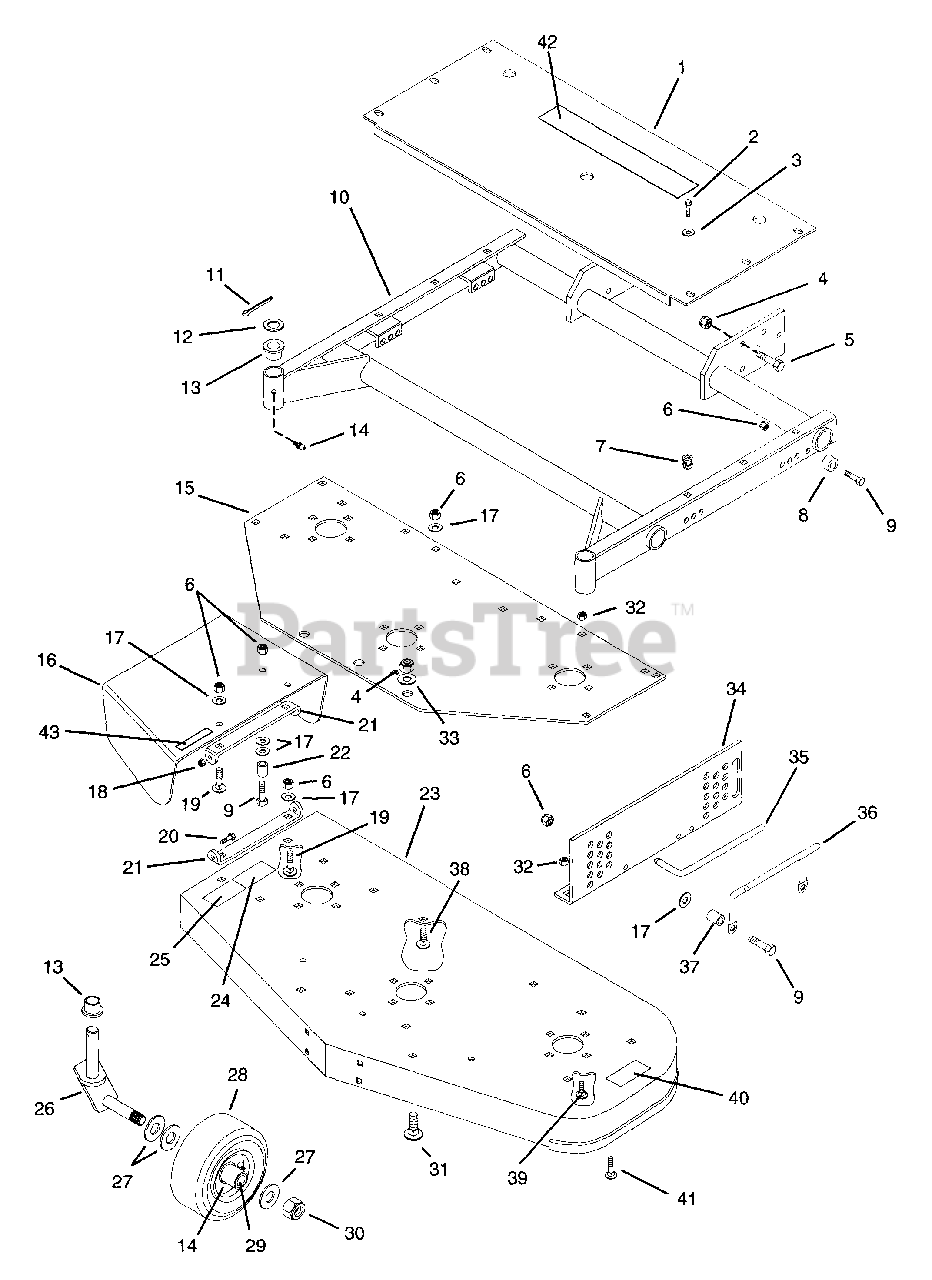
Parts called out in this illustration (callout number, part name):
1	Guard, 50"
2	Screw-Tapping, .25-20 x .50 Hex Slot Head
3	Washer-Flat-Steel .281 x .625 x .065
4	Nut, Locking .50-13
5	Bolt, Hex .50-13 x 1.50
6	Nut-Locking-Nylon .375-16 w/Insr Grade 2
7	Grommet, Plastic
8	Bushing, .391 x .626 x .670
9	Bolt-Hex .38-16 x 1.50 Grade 5
10	Weldment, Mower Frame
11	Pin, Cotter .187 x 1.50
12	Race, Bearing Thrust
13	Bushing-Flange 1.03 x 1.75 x .750 Nylon
14	Fitting, Lube .25-28
15	Plate, Support
16	Shield, Safety Ext. 50" Mower
17	Washer-Flat-Steel .406 x .812 x .065
18	Nut, Locking .25-20
19	Bolt, Round Head Square Neck .375-16 x 1.00
20	Bolt, Hex .25-20 x .875
21	Bracket, Chute
22	Stop, Chute
23	Weldment, 50" Mower Fabricated
24	Decal, Danger Hand
25	Decal, Warning Eye
26	Weldment, Caster Fork
27	Washer-Flat-Steel .812 x 1.496 x .134
28	Wheel, Guage 9 x 3.50
29	Bearing, Guage Wheel
30	Nut, Locking .75-10
31	Bolt, Round Head Square Neck .50-13 x 1.00
32	Nut, Locking .312-18 x .625
33	Washer-Flat-Steel 531 x 1.250 x .100
34	Bracket, Mower Sid Support Left Hand
34	Bracket, Mower Sid Support Right Hand
35	Pin, Mower Locking
36	Handle
37	Bushing
38	Bolt, Carriage .375-16 x .75
39	Bolt, Round Head Square Neck .312-18 x .625
40	Decal, Danger Foot
41	Bolt, Carriage .312-18 x 1.00
42	Decal, Gravely Logo
43	Decal, Width of Cut
